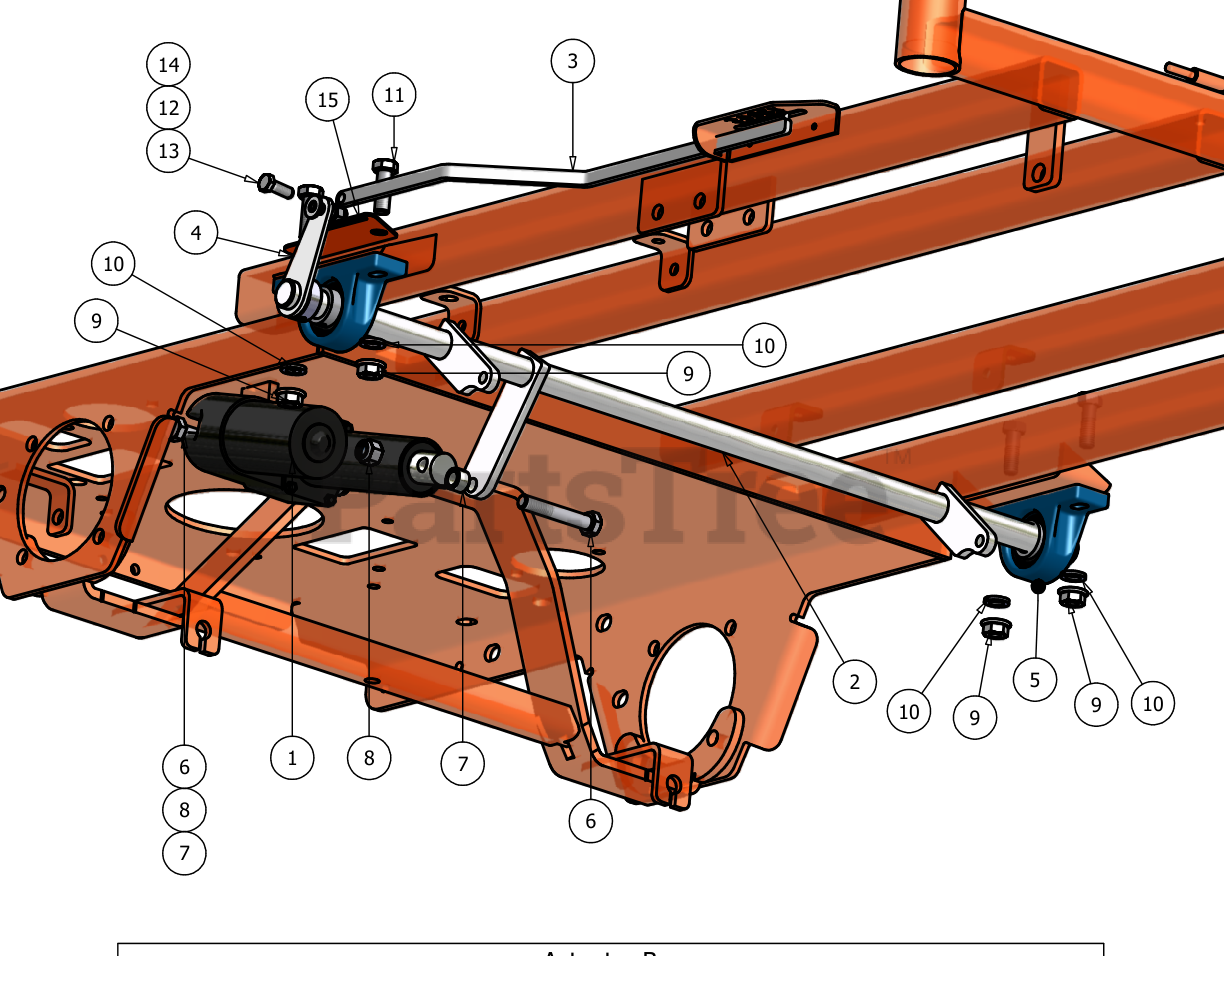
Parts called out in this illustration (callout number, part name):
2	Actuator Bar
3	Height Indicator
4	Height Indicator Tab
5	1" Pillow Block
6	1/2" x 3" Hex Bolt
7	1/2" x 1/2" Collar Spacer
8	1/2" Nylock Nut
10	1/2" Lock Washer
11	1/2" x 1 1/2" Hex Bolt
12	3/8" Plastic Washer
13	3/8" x 1" Hex Bolt
14	3/8 Nylock Nut
15	Deck Stop Bracket
